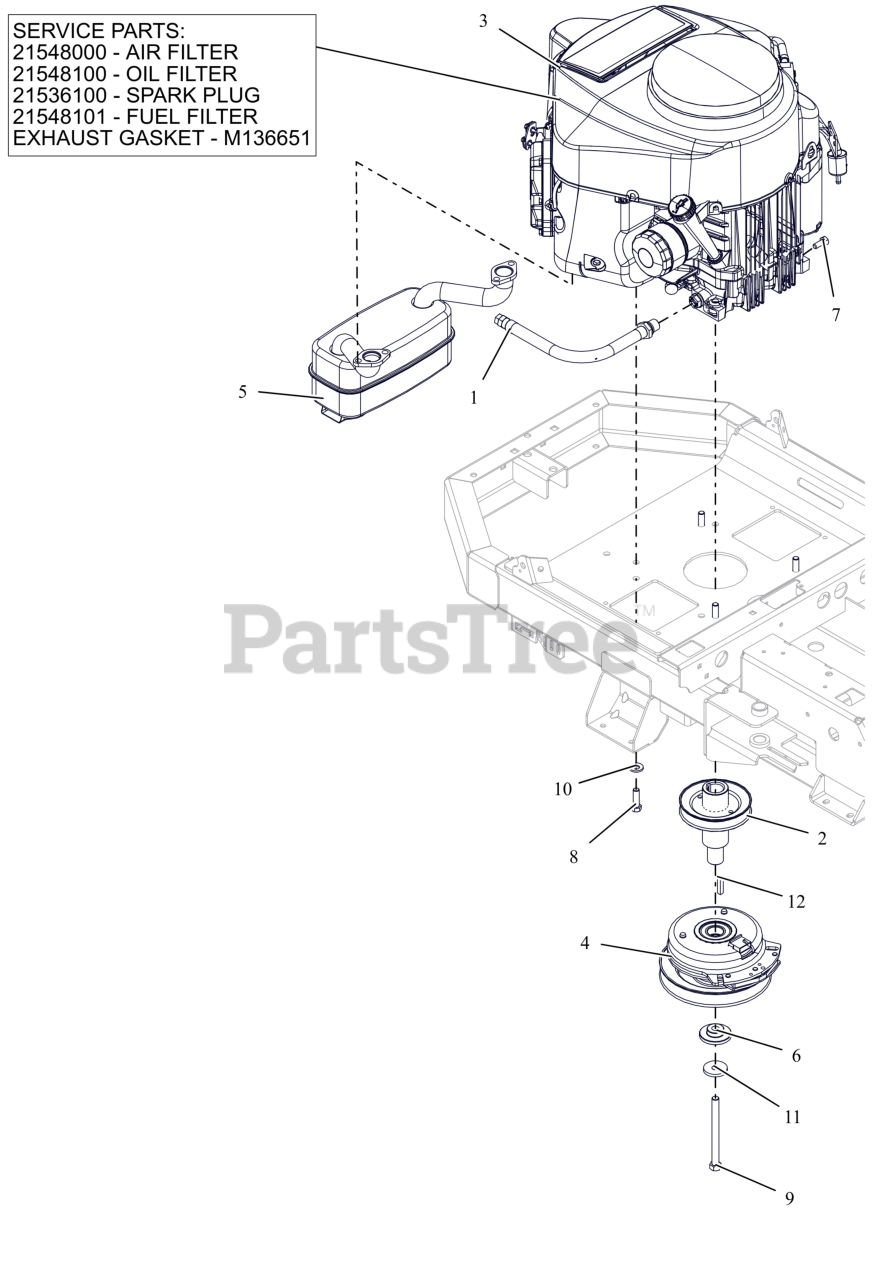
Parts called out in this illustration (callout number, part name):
1	HOSE, OIL DRAIN
2	WLDMT, DRIVE SHEAVE (LONG)
3	ENGINE, KAWASAKI FR691 23HP
3	AIR FILTER, KAWASAKI FR
3	OIL FILTER, KAWASAKI FR
3	PLUG, SPARK
3	FUEL FILTER-KAWASAKI FR
3	GASKET, MUFFLER #
4	CLUTCH,105FTLB MONOPOLE 6.83"
5	MUFFLER - KAWASAKI
6	BSHG-FLG .469X1.06X.574X2.0
7	BLT, HEX M8-1.25X20 G8.8 ZCC
8	BLT, HEX .38-16X1.25 G5 ZCC NT
9	BLT, HEX .44-20X5.00 G8 ZCC NT
10	WASHER, 3/8" SPRING DISC
11	WASHER, 7/16" SPRING DISK
12	KEY-SQ .25 X 1.25 X .25 SAE
